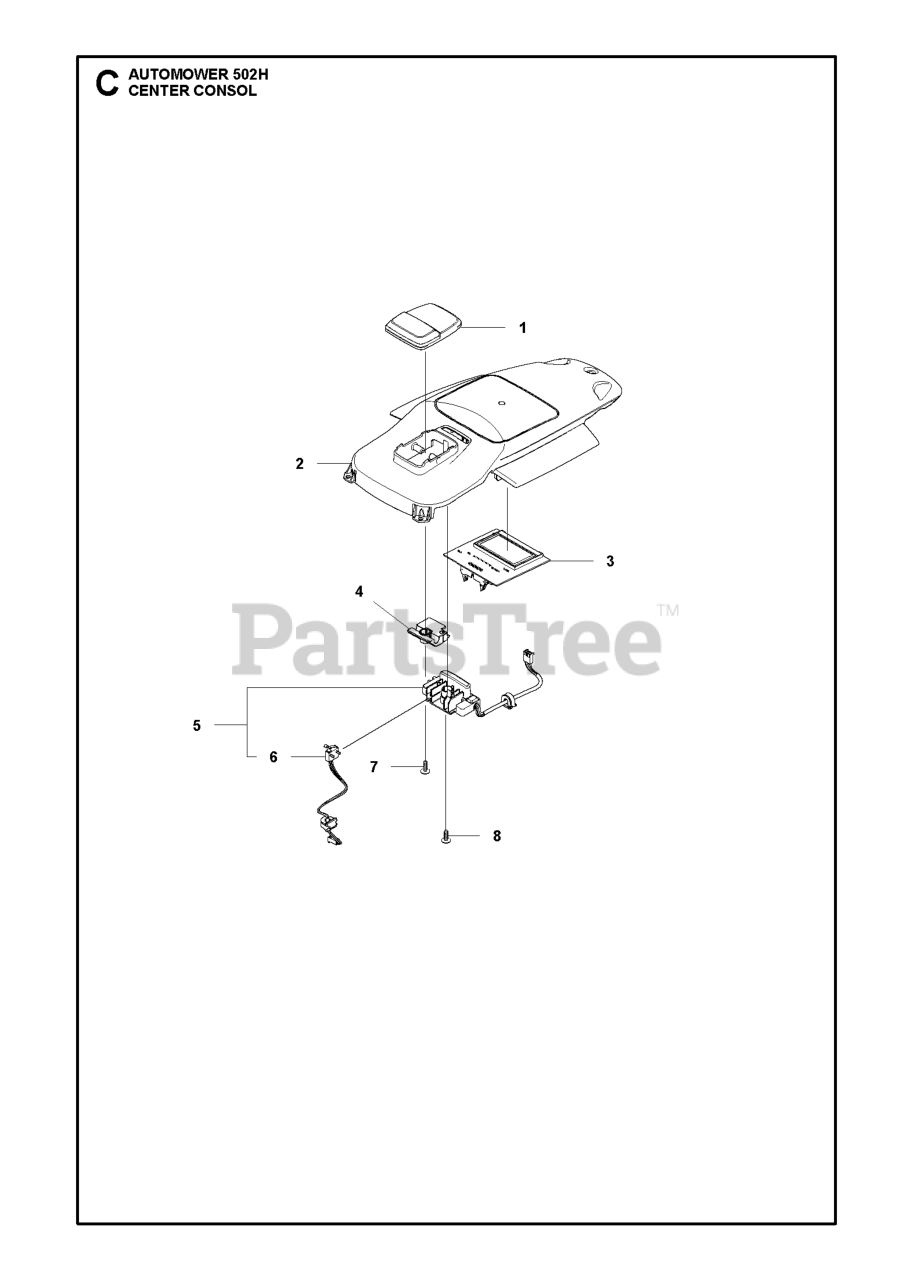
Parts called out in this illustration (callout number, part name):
1	BUTTON STOP
2	CONSOLE CENTER
3	PRINTED CIRCUIT ASSY HMI BOARD
4	SUPPORT BUTTON
5	HOUSING ASSY LED
6	SWITCH STOP BUTTON NO ANCHOR
7	SCREW 14MM
8	SCREW 14MM
